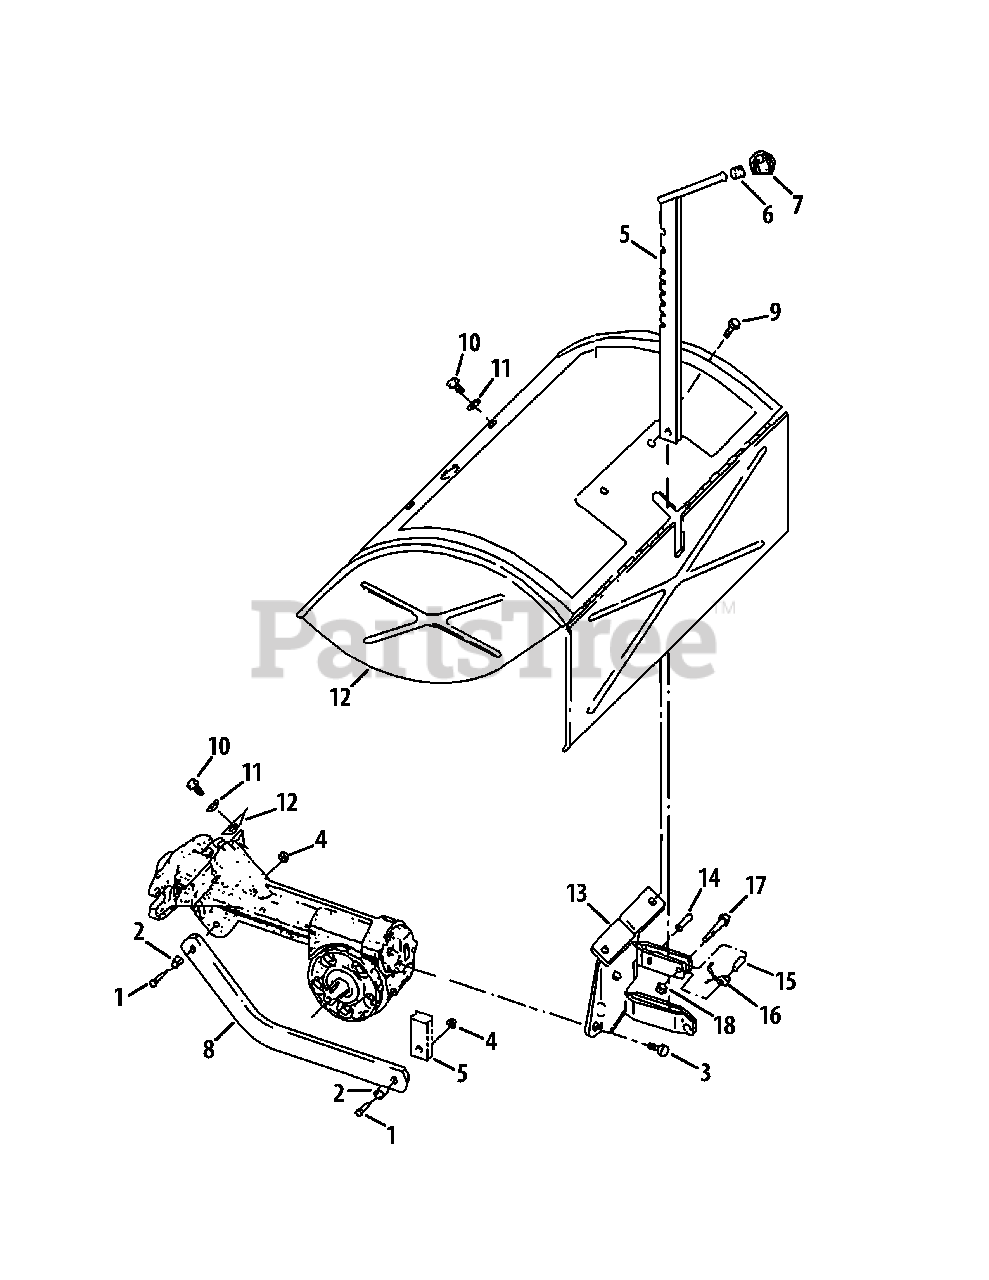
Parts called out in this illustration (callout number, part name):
1	Hex Bolt, 3/8"-16 x 1-1/4"
2	Bushing Spacer, 5 x 375 x 3
3	Hex Flange Bolt, 5/16"-18 x 625
4	Flangelock Nut, 3/8"-16
5	Depth Regulator
6	Retaining Ring
7	Depth Regulator Knob
8	Depth Regulator Bar Drag
9	Thread-forming Screw, 1/4"-20 x 1/2"
10	Hex Flange Bolt, 5/16"-18
11	Washer, 112 x 34 x 06
13	Hood Bracket
14	Roll Pin (Spirol), 1/4" x 1"
15	Split Spacer
17	Hex Bolt, 1/4"-20 x 1"
18	Locknut, 1/4"-20
